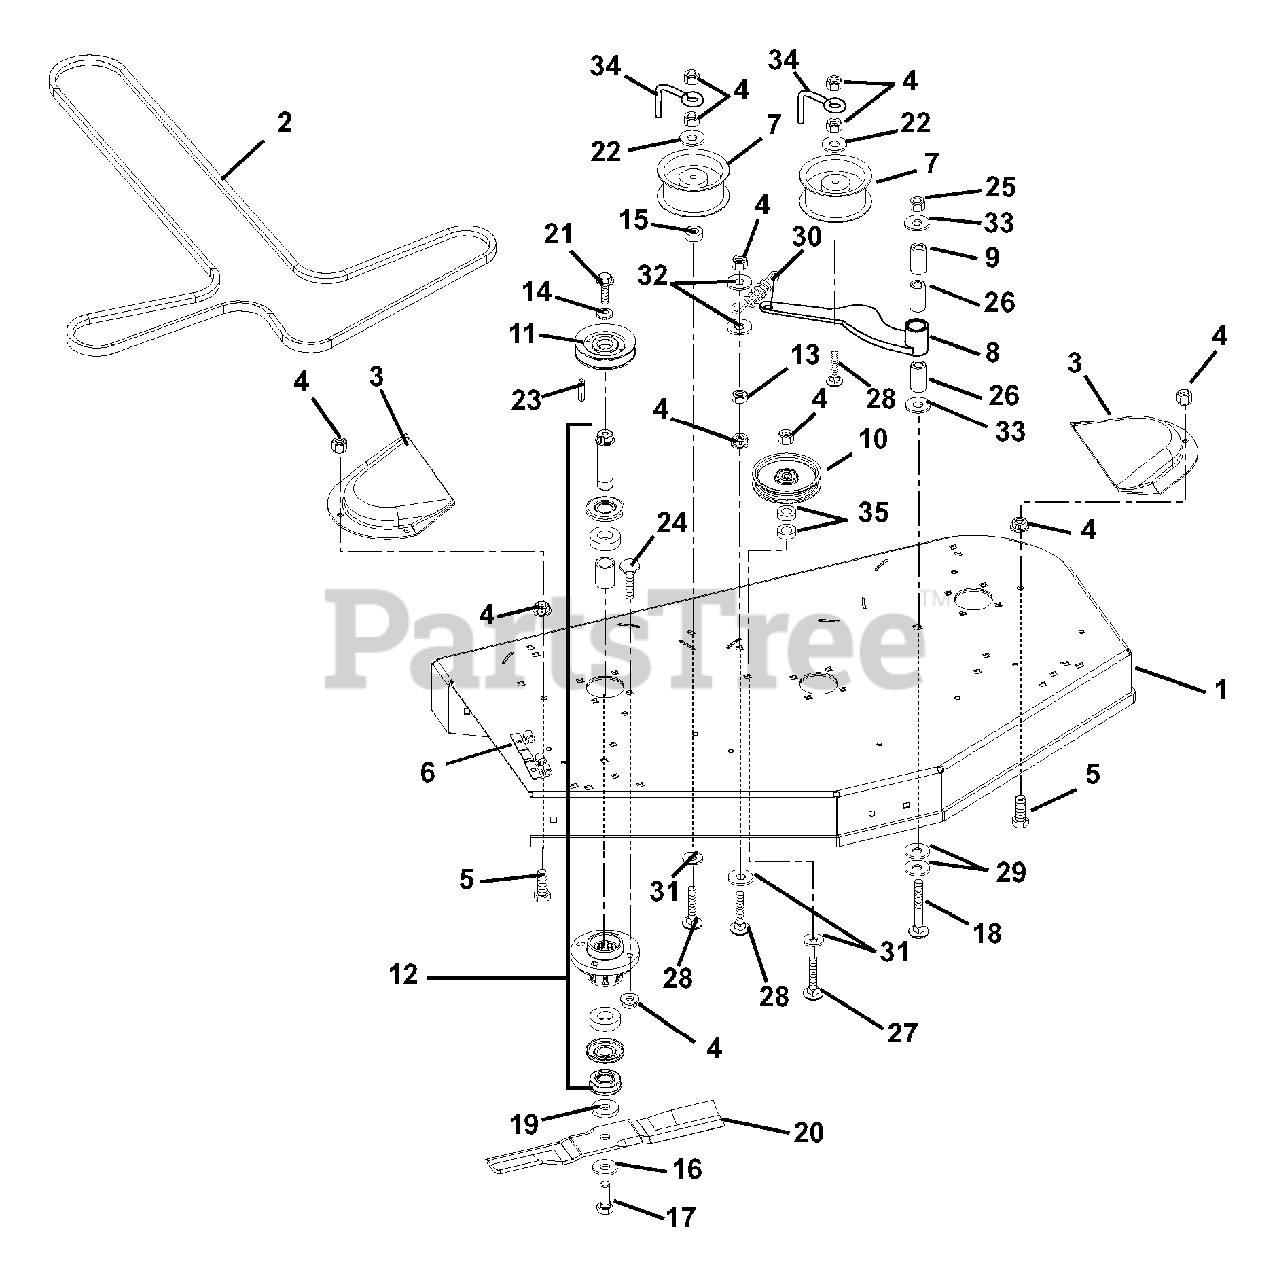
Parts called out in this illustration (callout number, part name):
1	40" MOWER DK W/DECALS C-L2078
1	40" MOWER DECK ASSY COMPLETE
1	44" MOWER DK W/DECALS C-L2078
1	44" MOWER DECK ASSY COMPLETE
1	44"CE DECK ASSY (SERVICE)
1	40"CE DECK ASSY (SERVICE)
1	48" MOWER DK W/DECALS C-L2078
1	48" MOWER DECK ASSY COMPLETE
1	52" MOWER DK W/DECALS C-L2078
1	52" MOWER DECK ASSY COMPLETE
2	V-BELT, HA-WRAPPED
2	BELT,HA WRAPPED
4	@NUT-LK-NYL-FLG .38-16 YWZC
5	@BLT-HEX .38-16X1.25 GR5 YWZC
6	HINGE PLATE
7	IDLER FLANGED 3.50
8	WELDMENT, IDLER ARM
9	BSHG, SPCR .502X.997X2.03 PM
10	IDLER-FLAT 4.00 X .38 NWHAMSHR
11	SHEAVE, SPINDLE - 4.00 DIA.
11	SHEAVE, SPINDLE - 4.75 DIA.
11	SHEAVE, SPINDLE - 4.25 DIA.
11	SHEAVE, SPINDLE - 4.50 DIA.
12	ASSEMBLY, SPINDLE
13	@NUT-LK-CTR-JAM .375-16 YWZC
14	WASHER, CUPPED SERRATED, .375
15	SPACER, .39 X 1.50 X .380
16	WSHR-BLVL .669X1.535X.138
17	BLT-HEX .62-18X1.75 GR8 YWZC
18	@BLT-RDHDSQNK .50-13X3.50 G5YZ
19	WSHR-FLT .640X1.75X.250 YWZC
20	MOWER BLADE, 13.94"
20	BLADE, 15.50"
20	BLADE, MOWER (16.19")
20	BLADE, MOWER (18.00")
20	BLADE, MULCH 15.50"
20	BLADE, MULCH 13.88
21	BLT-HEX .38-16X1.00 YZ GR8
22	WSHR-FL-STL .406X1.00X.188 YWZ
23	KEY, SQ .25 X .38 X .25
24	@BLT-RDHDSQNK .38-16X1.50 G5YZ
25	@NUT-LK-TOP-FLG .50-13 YWZC
26	BRG, 1.00 X 1.12 X .75
27	@BLT-RDHDSQNK .38-16X1.75 G5YZ
28	@BLT-RDHDSQNK .38-16X2.75 G5YZ
29	WSHR-FL-STL.755X1.375X.062YWZC
30	SPRING, EXTENSION
31	@WSHR-FL-STL.531X1.06X.095YWZC
32	WSHR-FL-STL .375X1.125X.065YWZ
33	WSHR-FL-STL .515X1.625X.250 YZ
34	FINGER - BELT
35	WSHR-FL-STL .380X1.50X.125YWZC
